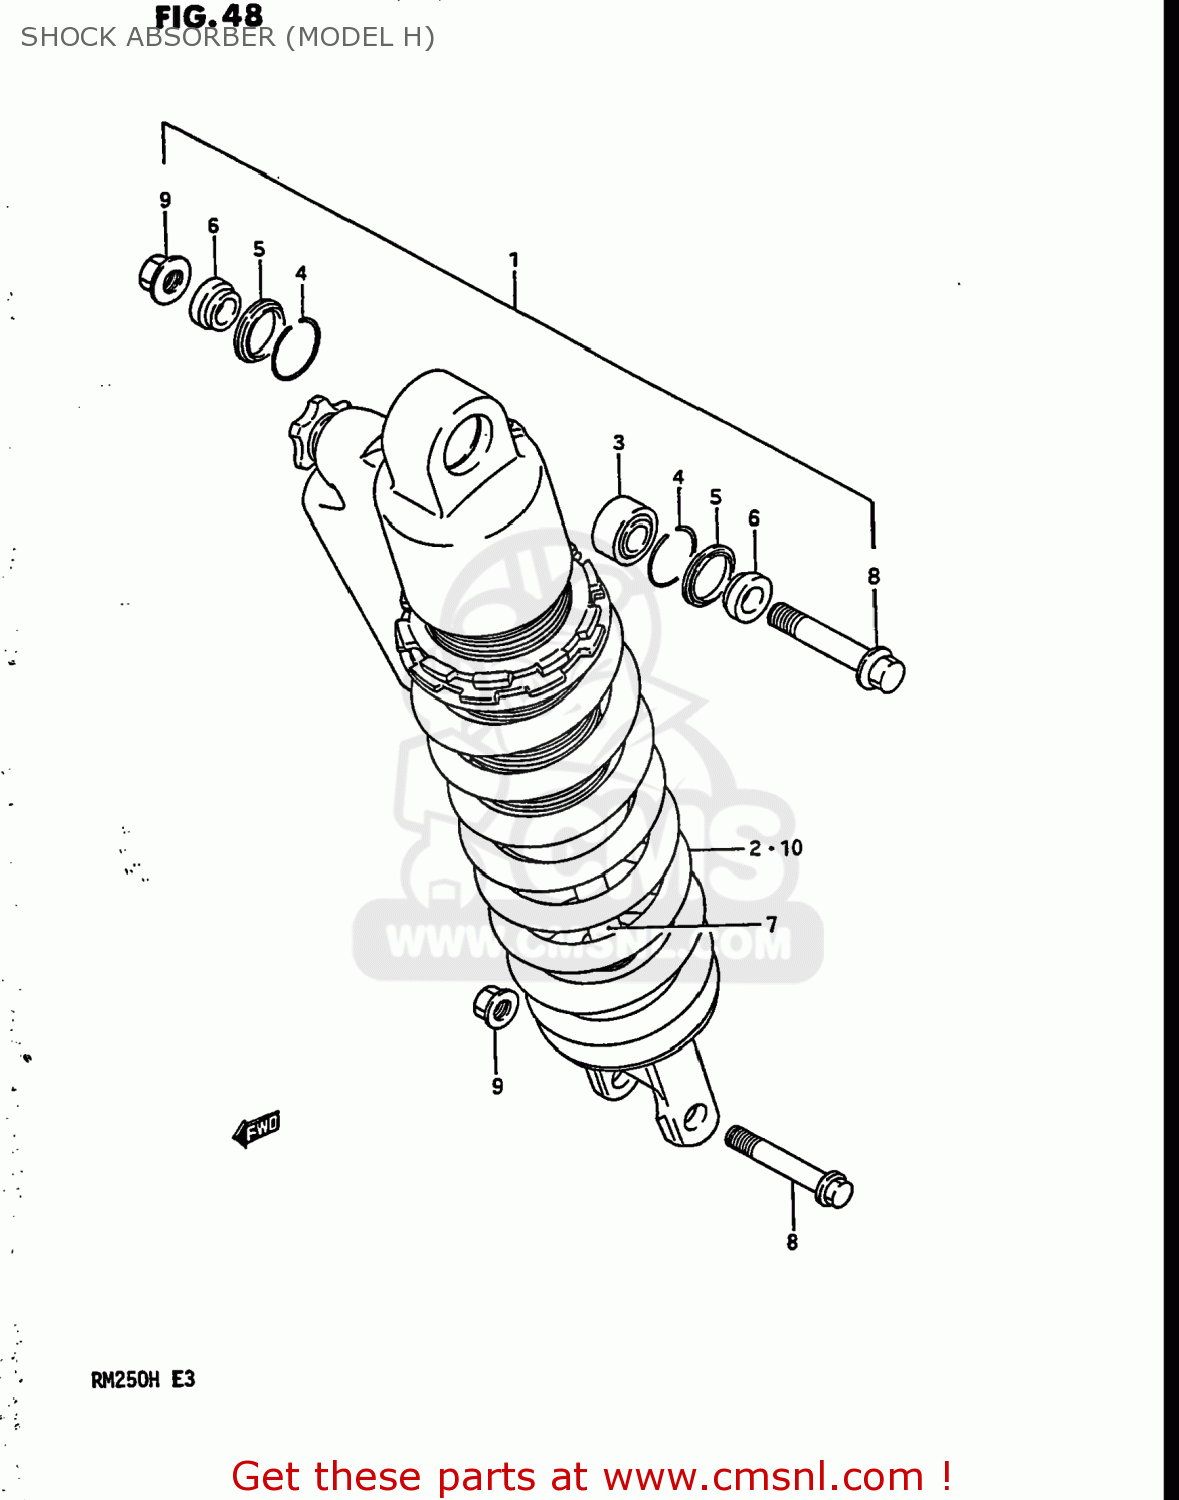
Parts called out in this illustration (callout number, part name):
1	ABSORBER ASSEMBLY,REAR SHOCK
2	SPRING
3	BEARING,RR CUSHION LEVER
4	RING
5	DUST SEAL
6	SPACER
7	ROD,PISTON
8	BOLT,REAR SHOCK ABSORBER
9	NUT
10	SPRING
